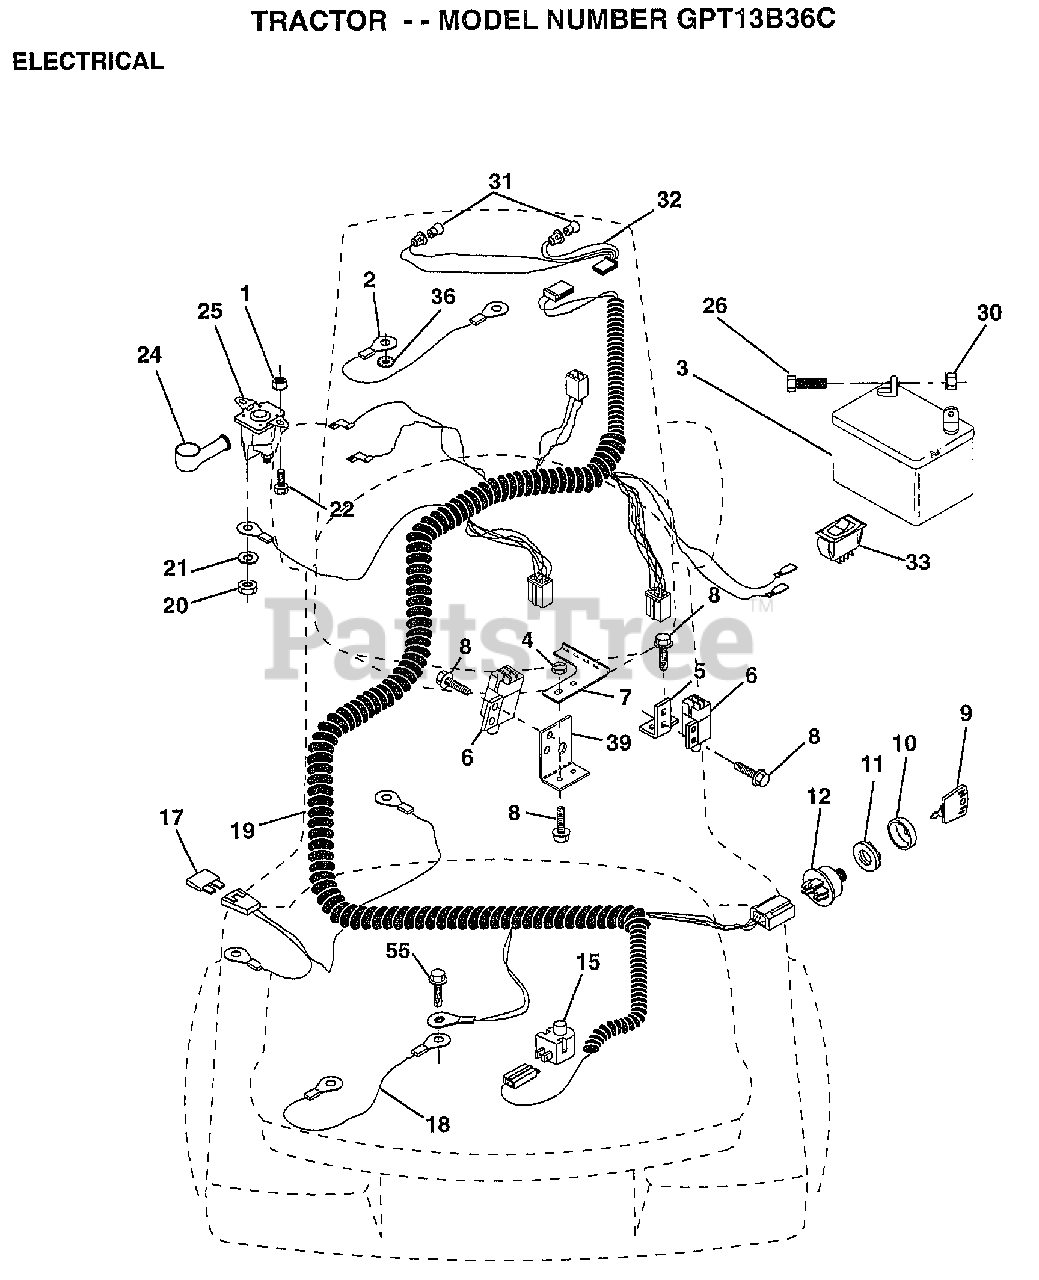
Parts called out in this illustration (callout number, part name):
1	NUT HXKEP 1/4X20
4	LOCKNUT
5	BRACKET LT
6	SWITCH INTERLOCKT
7	KEEPER.ACTUAT.LR.
8	SCREW
9	KEY MLD GEN DELTA
10	COVER KEY SWITCH
12	SWITCH.IGNITION
15	SWITCH SEAT
17	FUSE HYT
18	CABLE ASSY
19	HARNESS.IGN.LR.
20	NUT
22	BOLT HXHD FIN
26	BOLT LT
30	NUT
31	HEADLAMP BULB
32	"HARNESS,LIGHT SOC"
33	SWITCH LT
36	LOCKWASHER
39	BRACKET SWT CLUTC
55	SCREW LT
